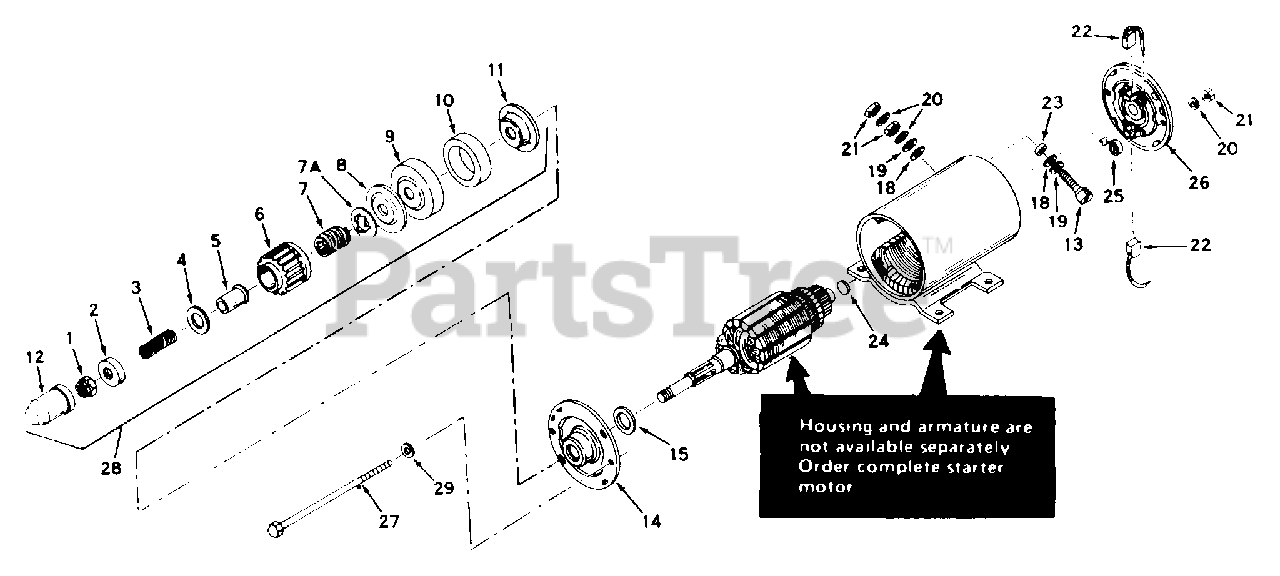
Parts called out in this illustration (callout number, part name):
1	"Nut, Hex
2	Stop, Pinion
3	Spring, Anti-drift
4	Washer, Pinion
5	Sleeve, Anti-drift
6	Gear, Pinion
7	Shaft, Screw
7A	Stopper, Screw
8	Washer, Thrust
9	Cap, Cushion
10	Cushion, Rubber
11	Washer, Thrust
13	Bolt, Terminal
14	Cap Assy., Drive end
15	Washer, Spacing (.024 thick)
15	Washer, Spacing (.008 thick)
18	Washer, Insulating
19	Washer, Plain
20	Washer, Lock
21	Nut, Hex
22	Brush & Spring Kit
23	Bushing, Insulating
24	Washer, Spacing
25	Spring, Brush
26	End Cap Assy., Commutator
27	Bolt, Thru
28	Drive Assy., Complete
